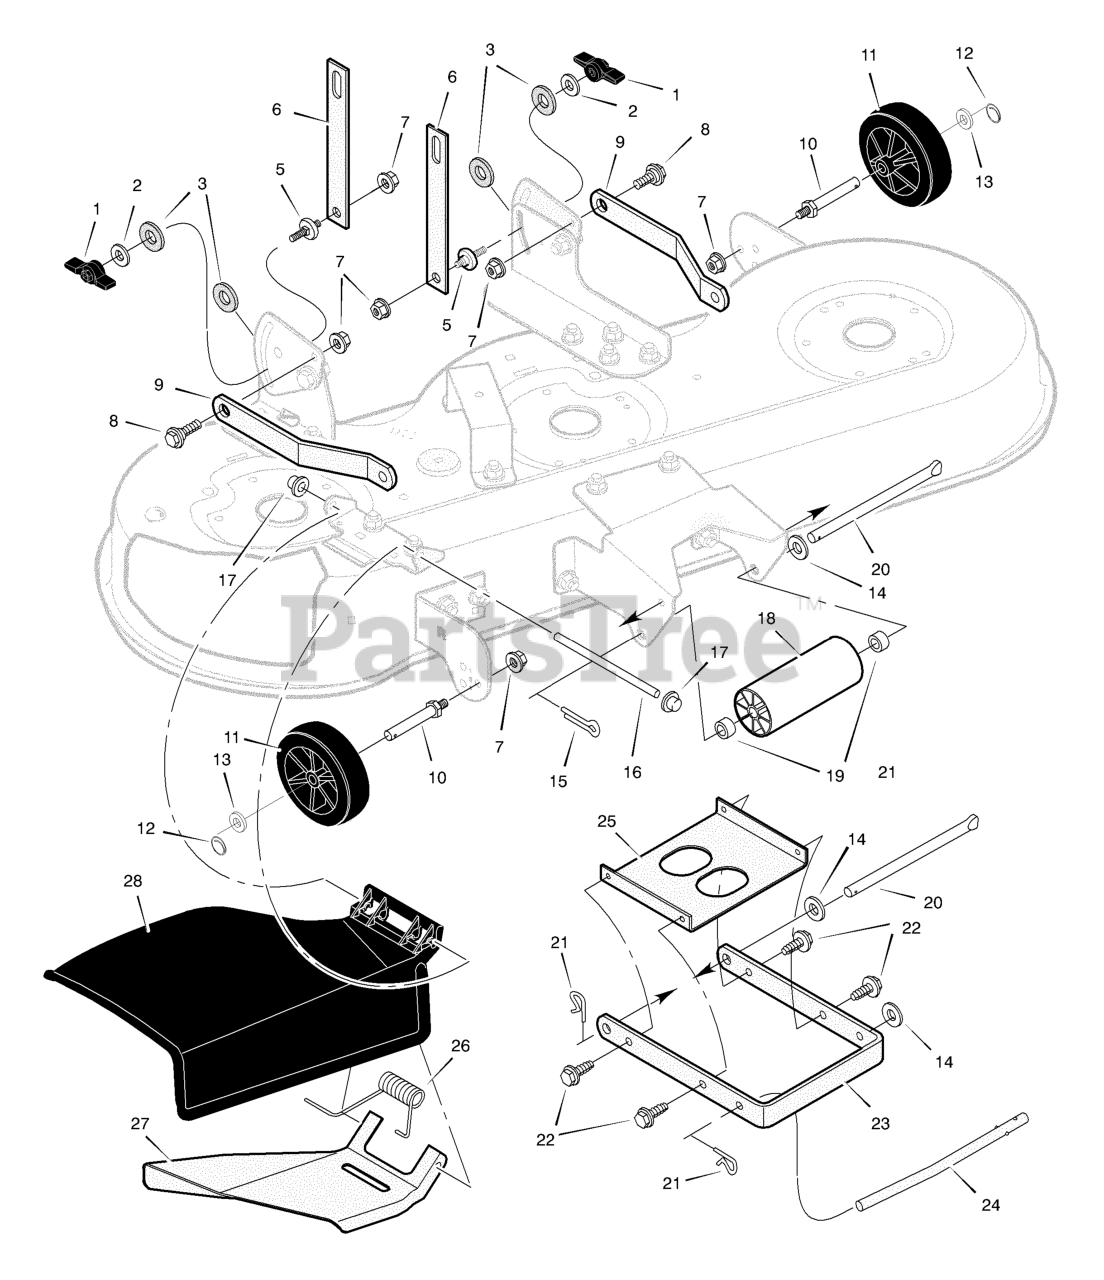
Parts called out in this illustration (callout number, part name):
1	Knob
3	Pad, Friction
5	Pin, Hanger
6	Link, Lift
7	Nut, Flange
8	Bolt, Shoulder
9	Bracket, Rear Suspension
10	BOLT, Gauge Wheel
12	Pin, Hair
15	Pin, Cotter
16	Rod, Deflector
17	Push-On Cap
20	Rod, Deck Suspension
21	Pin, Hair
23	Bracket, Front Suspension
24	Rod, Hanger
25	Stiffener
27	Deflector, Inside
28	Deflector, Chute
